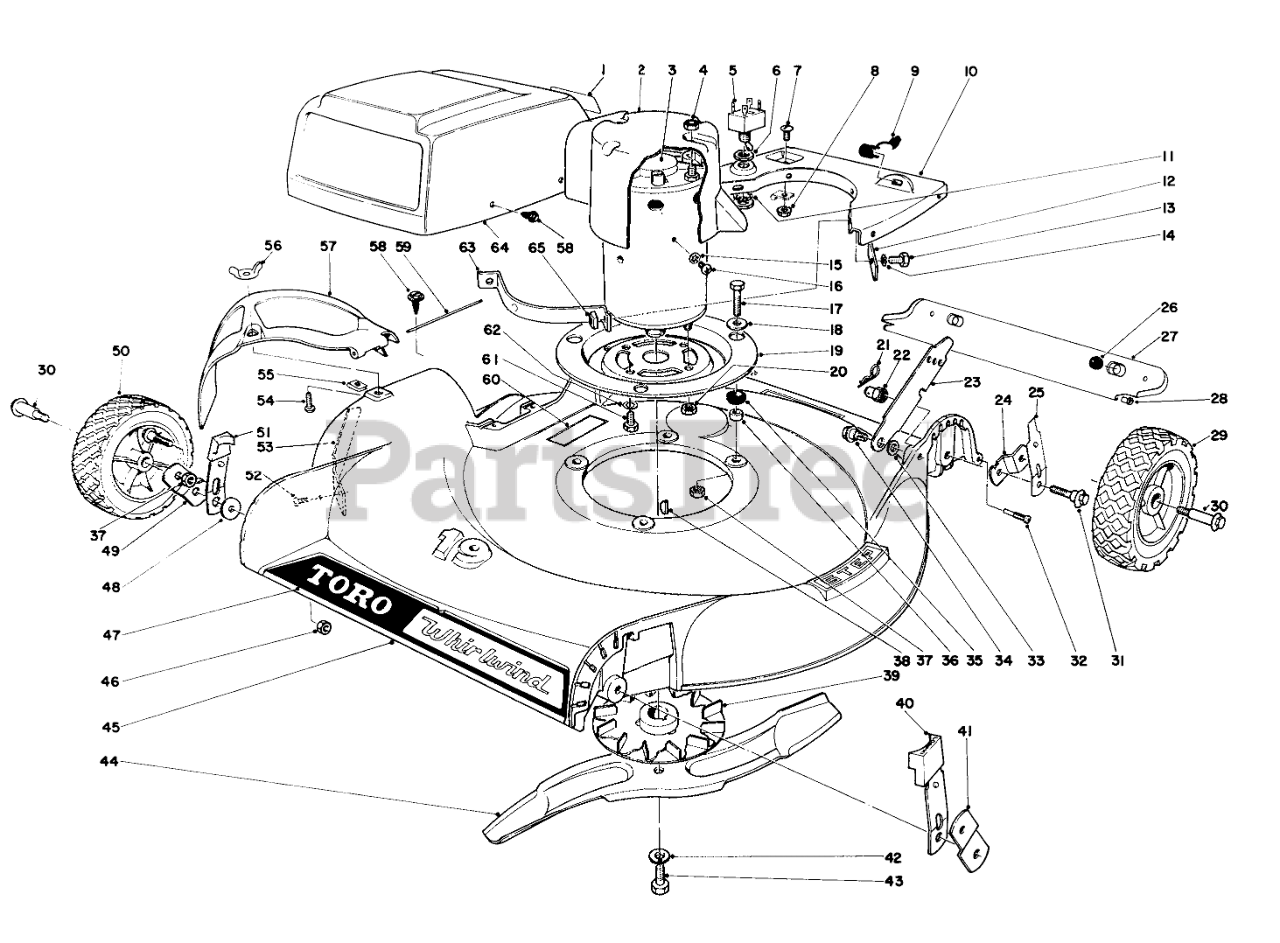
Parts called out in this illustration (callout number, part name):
1	Decal U.L.
2	Cover-Switch & Motor
3	Motor
5	Switch
7	10-24 X 5/8 PAN HD MS
8	NUT-KEPS
9	Strain Relief
10	Support Shroud
11	Lockwasher
12	Washer Support
13	SCREW-HH
14	WASHER-LOCK/EXT
15	WASHER-LOCK/INT
17	SCREW-HH
18	WASHER-FLAT
19	Motor Support Plate
20	Nut
21	PIN-COTTER, HAIR
22	HANDLE PIVOT NUT
23	Latch
24	Pivot Arm
25	Spring Arm
26	SKID BUTTON
27	Rear Safety Shield (Incl. Ref. 26 & 28)
28	SAFTEY SHIELD BUSHING
29	WHEEL ASM 8
31	PIVOT SCREW
32	SAFTEY SHIELD SCREW
33	SPACER
34	SCREW-SHOULDER
35	GROMMET
36	Spacer-Split
37	Nut
38	KEY-WOODRUFF
39	Fan & Blade Retainer
40	Arm Knob
41	Pivot Arm
42	WASHER-LOCK
43	SPECIAL SCREW
44	Blade
45	Housing
46	Nut
47	Decal
48	WASHER-PIVOT
49	Pivot Arm
50	WHEEL ASM 7
51	Arm Knob
53	Bar Safety
55	NUT-SPEED
56	NUT-WING SPECL
57	Deflector
58	SCREW-HWHTF
59	HINGE PIN
60	Decal
61	SCREW-HH
62	WASHER-LOCK, INTERNAL
63	Clamp-Shroud Support
64	Shroud
65	NUT-SQUARE
